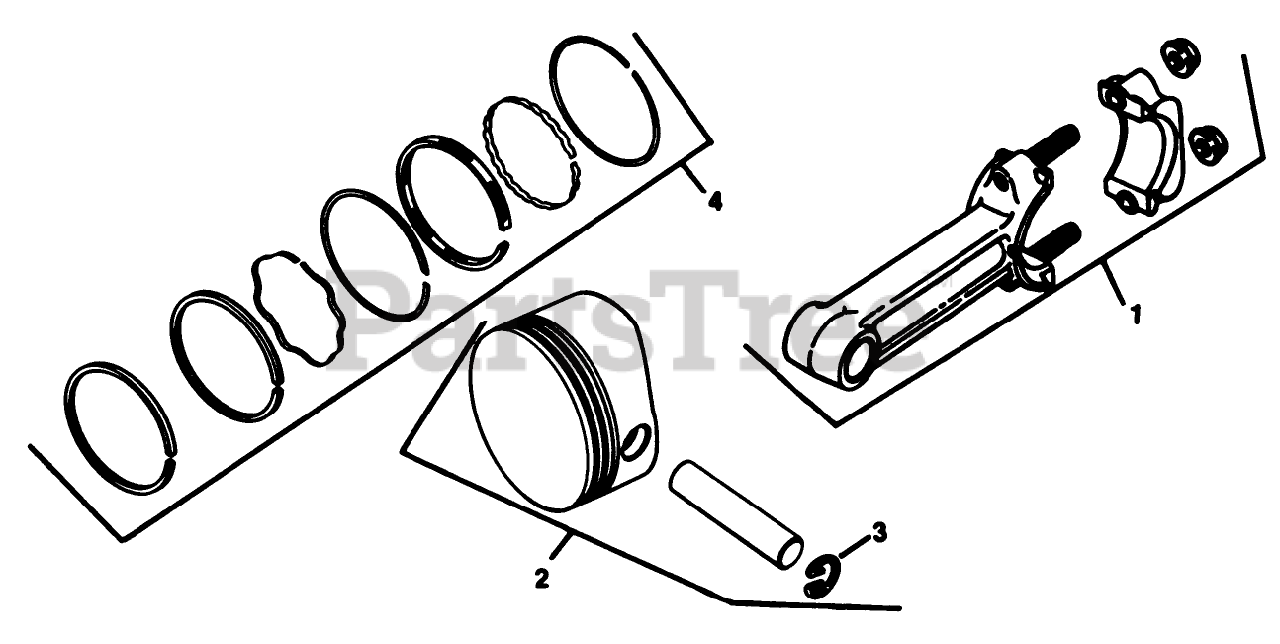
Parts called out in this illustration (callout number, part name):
1	Rod-Connecting Std.
1	Rod-Connecting .010"
2	Piston & Ring Set Std.
2	Piston & Ring Set .003"
2	Piston & Ring Set .010"
2	Piston & Ring Set .020"
2	Piston & Ring Set .030"
3	Retainer, Pin
4	Ring Set Std. & .003"
4	RingSet.010"
4	Ring Set .020"
4	Ring Set.030"
